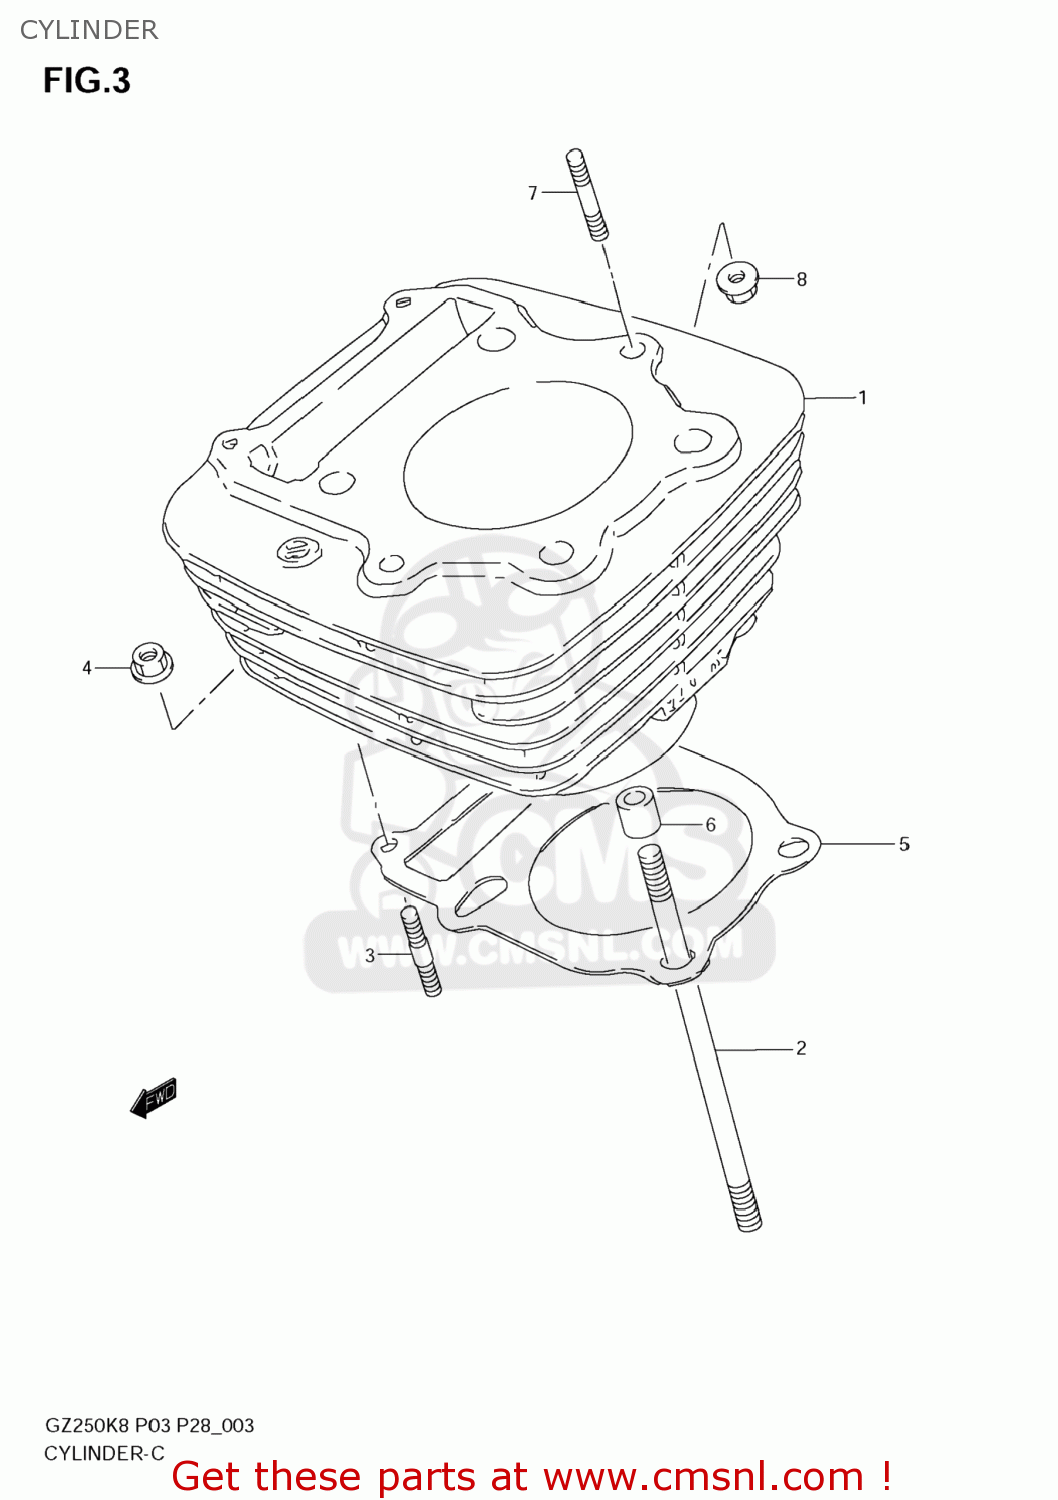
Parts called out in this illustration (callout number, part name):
1	CYLINDER
2	BOLT,STUD
3	BOLT,STUD
4	NUT
5	GASKET,CYLINDER (NAS)
6	PIN
7	BOLT,STUD
8	NUT
